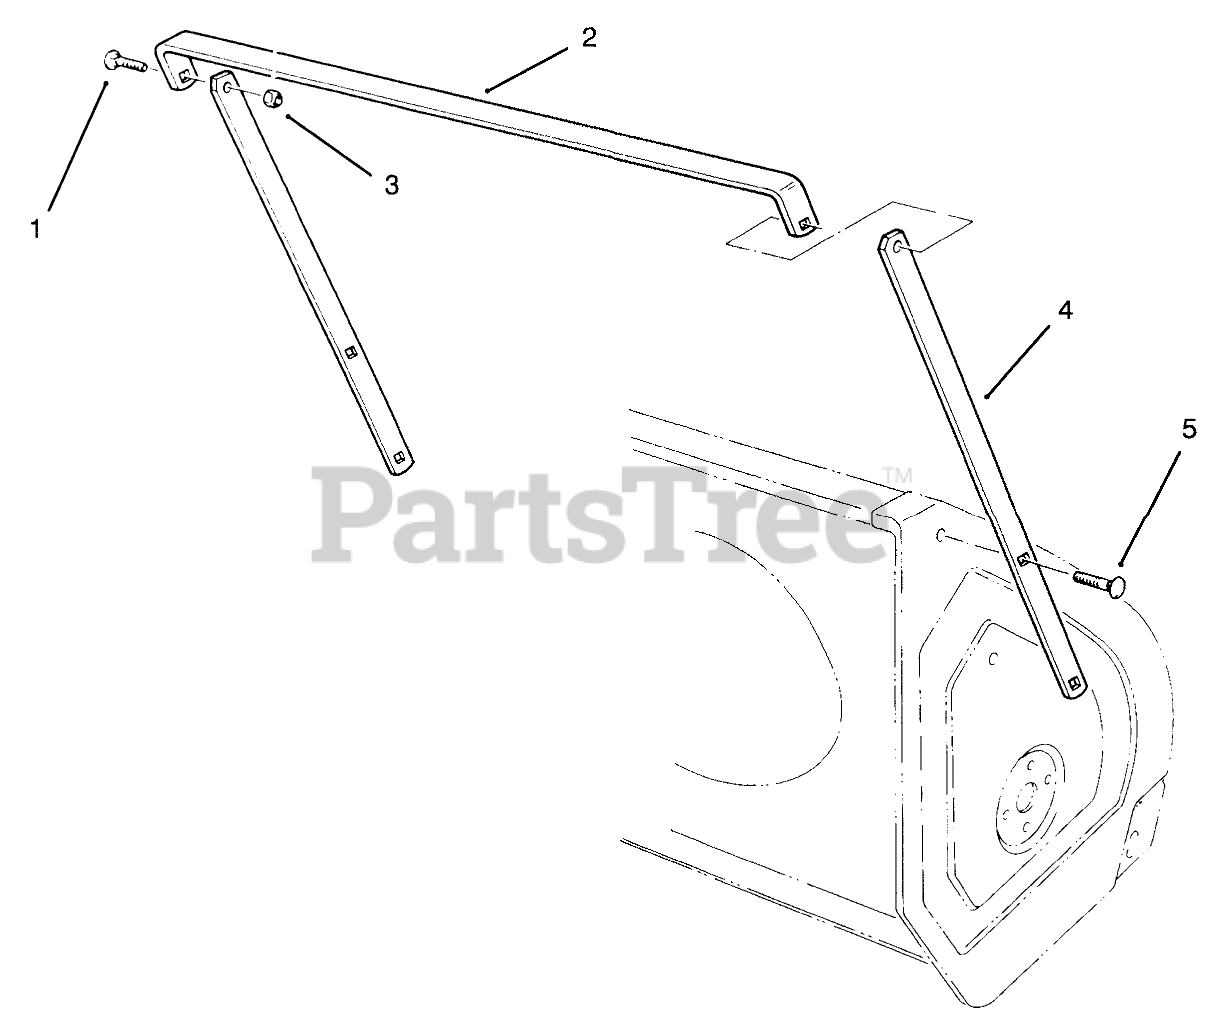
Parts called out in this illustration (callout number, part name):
1	SCREW-CARR
3	NUT-LOCK, NI
4	Breaker-Side
5	BOLT-CARR
